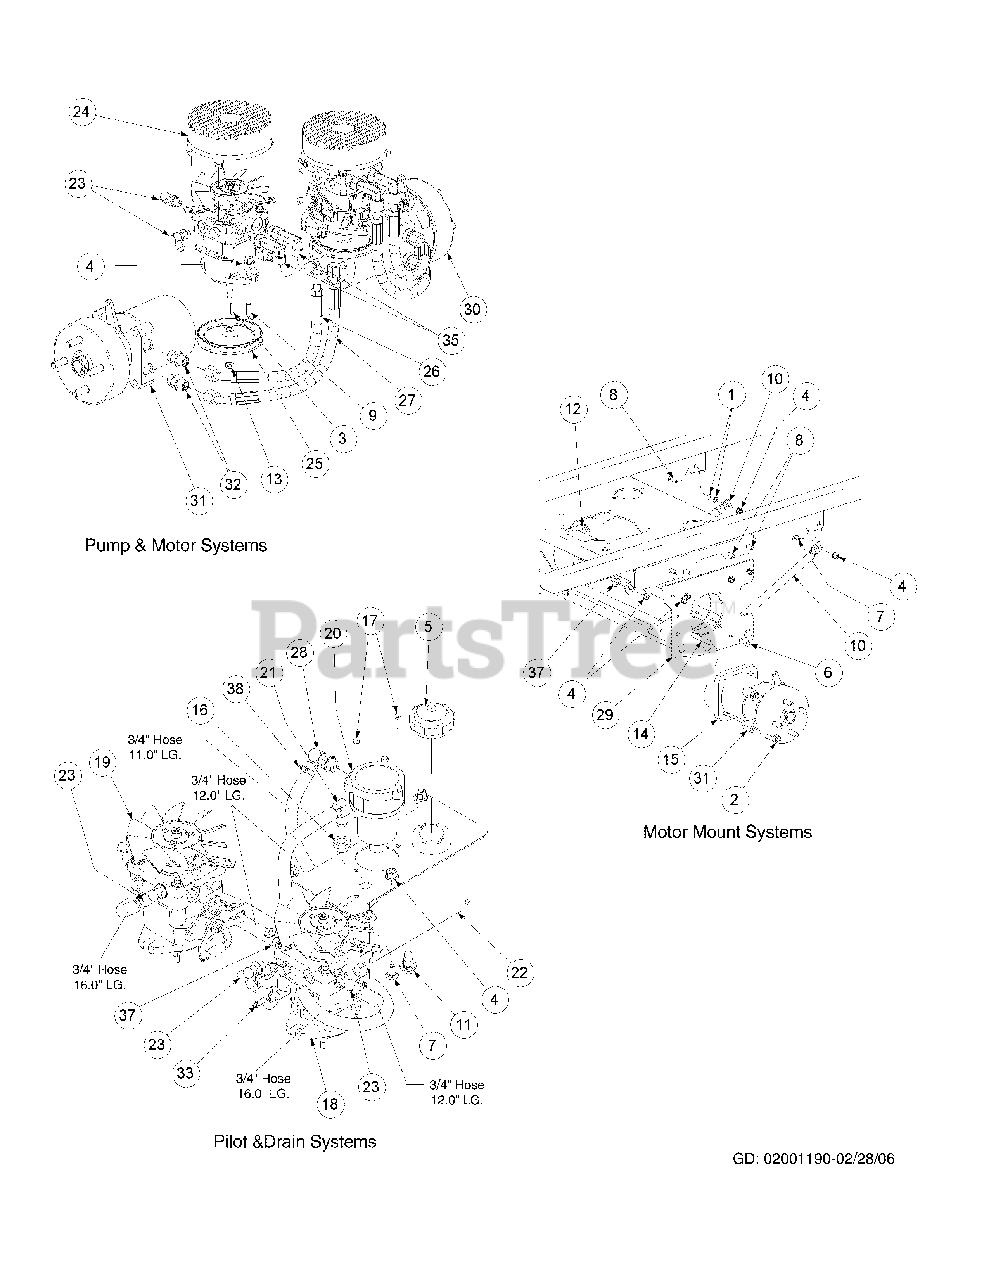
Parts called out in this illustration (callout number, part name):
1	Washer lock 3/8 zinc
2	Washer lock 3/8 zinc
3	Key, 3/16" x 7/8"
4	Flange Lock Hex Nut, 3/8-16
5	Cap, Hydro Oil Tank
6	Hex Cap Screw, 3/8 -16 x 1.25
7	Carriage Bolt, 3/8-16 x .75 LG.
8	Carriage Bolt, 3/8-16 x 1
9	Carriage Screw, 3/8-16 x 1.25
11	Oil Pan Drain Plug w/ Seal
12	Hydro Wheel Motor Backup Plate
13	Hex Nut, 3/8-24
14	Socket Head Capscrew, 1/2-13; 3-1/2
15	Hydro Motor Spacer
16	Grommet Fitting, .54 ID x .78 OD
17	Socket Low Head Cap Screw, 1/4-20 x 0.75
18	Hydro Pump, BDP-12, RH
19	Hydro Pump, BDP-12, LH
20	Hydraulic In-Tank Filter includes:
21	Fitting Elbow Spur, 5/8 x 1/2
22	Hydraulic Tank Assembly
23	Fitting Elbow, 9/16 x 1/2
24	Fan Pump Shroud
25	Hydro Pump Pulley
26	Short Pressure Hose Assembly
27	Long Pressure Hose Assembly
28	Fitting Elbow, 3/4 x 1/2
29	Hydro Motor Frame Assembly
30	Hydro Motor, Left Hand Assembly w/ Brake & Drum
31	Hydro Motor, Right Hand Assembly w/ Brake & Drum
32	Adaptor Fitting, 8 x 10
33	Hose Clamp
34	Fuel Hose, .50 ID x .75 OD (79 in inches)
35	Adaptor, 8 x 8
36	Spacer .406 ID x 1.0 OD
37	Tee Fitting, 1/2
38	Hose Clamp, 1/2
